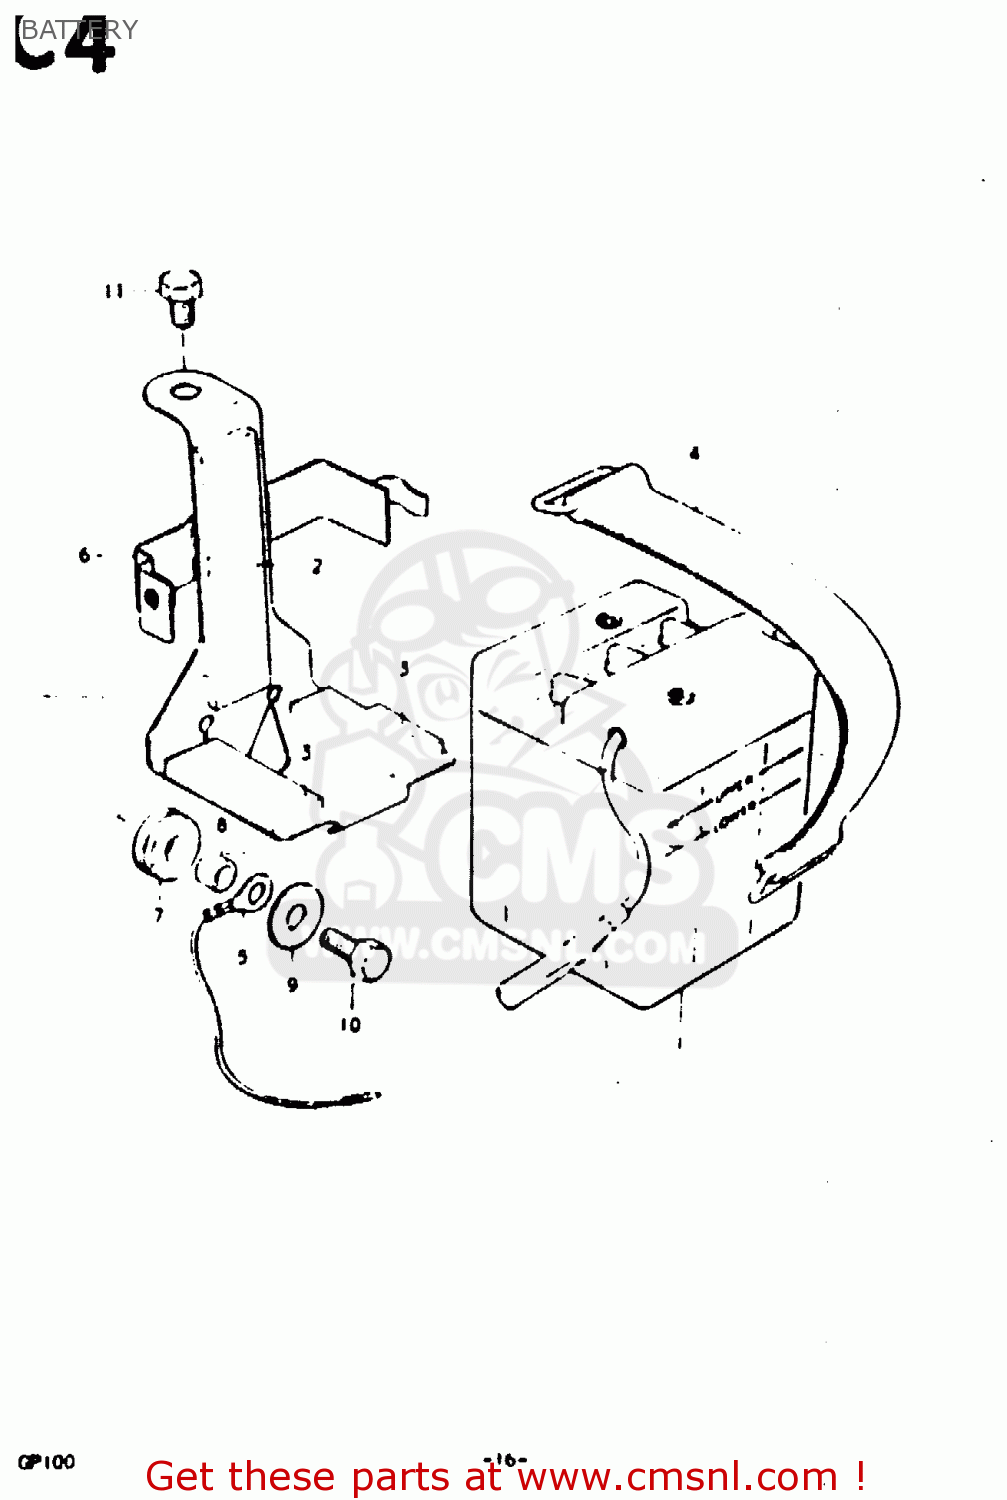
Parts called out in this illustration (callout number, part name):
1	BATTERY ASSY(6N4-2A4.2AH)
2	PROTECTOR(170X95X3.0)
3	PROTECTOR(170X95X3.0)
4	BAND
5	LEAD WIRE
6	HOLDER,BATTERY
7	CUSHION
8	SPACER(6.1X9X7.5)
9	WASHER
10	BOLT, UPPER
11	BOLT
